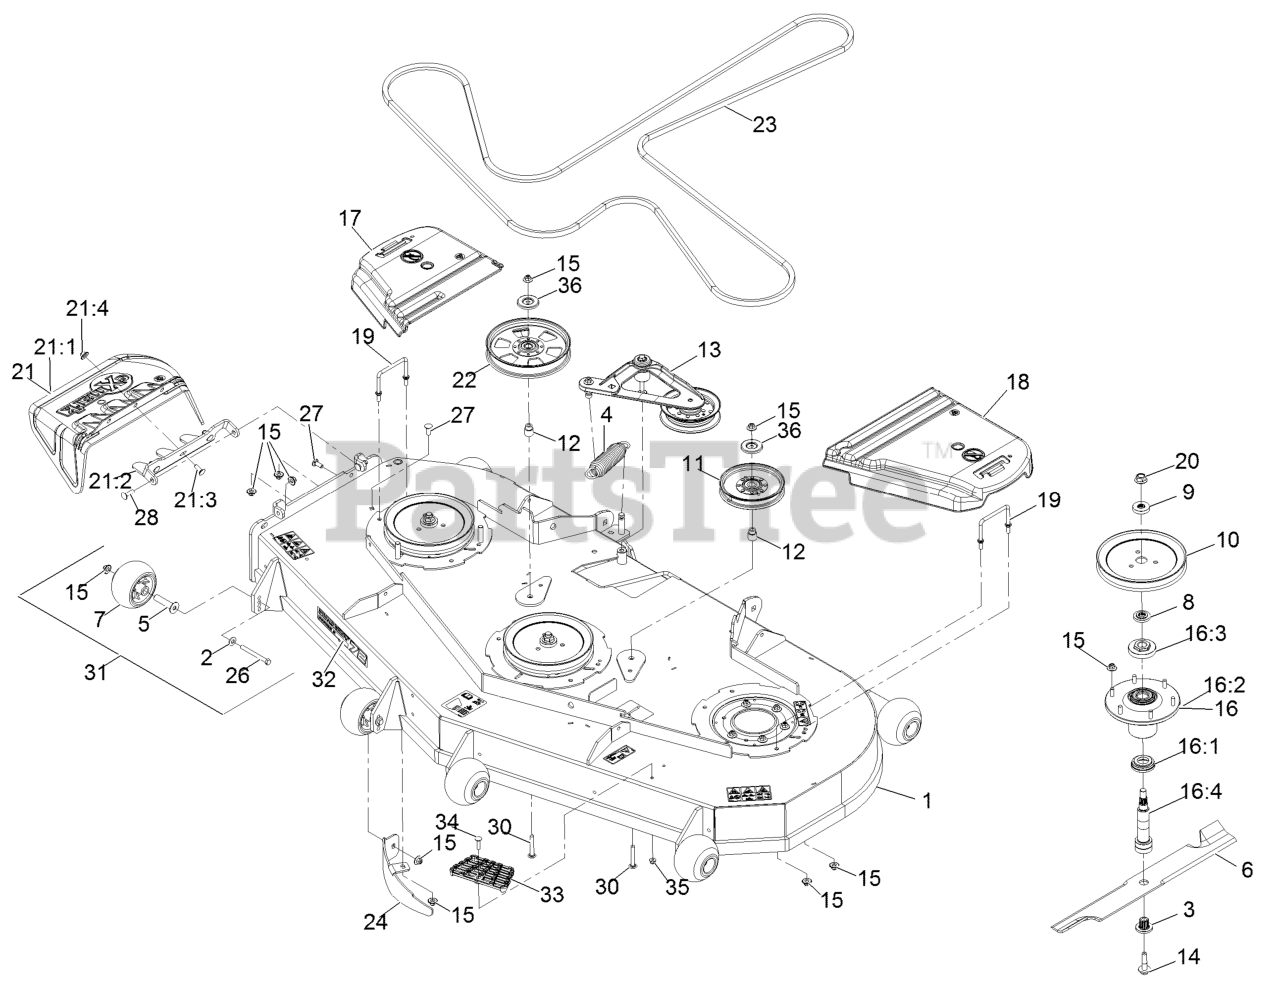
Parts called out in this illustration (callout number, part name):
1	ASM,Deck W/Decals 724
2	Washer-Spring Disc 3/8
3	Bushing, Splined
4	Spring-Extension
5	Axle, Roller
6	Blade-Extreme 2, 24.50"
6	Blade, Notched (72")
6	Blade, Mulching (72")
6	Blade, Low Lift (72")
6	Blade, Solid (72")
7	Roller-Anti-Scalp
8	Spacer, Splined Stepped
9	Spacer, Splined
10	Sheave,Blade Drive 9.00
11	Idler-Pulley, Flat 6.00X0.75
12	Bushing, Idler
13	Deck Idler ASM
14	Screw-Sems 1/2-20 X 2.19
15	Nut-Nyloc 3/8-16 Flg
16	ASM,Spindle Housing
16:1	Guard, Bottom
16:2	Asm, Cutter Housing
16:3	Nut, Spindle 7/8-14
16:4	Spindle,Double Spline
17	Cover-Belt, RH
18	Cover-Belt, LH
19	Wireform-Cover
20	Nut-Flange 5/8-18 Centerlock
21	ASM,Discharge Chute
21:1	Chute, Discharge
21:2	Bracket,Discharge Chute
21:3	Bolt-Carriage 3/8-16 X 1
21:4	Nut-Nyloc 3/8-16 Flg
22	Pulley-Idler, Flat
23	Belt-V
24	Baffle-Dogleg, Lz72
26	Screw-HH 3/8-16 X 3 3/4 GR 8
27	Bolt-Carriage 3/8-16 X 1
28	Bolt-Carriage 3/8-16 X 1 1/4
30	Bolt-Carriage 3/8-16 X 2 1/2
31	Kit, Anti-Scalp Roller
32	Decal, 726
33	Step-Deck
34	Bolt-Carriage 5/16-18 X 1 1/4
35	Nut-Nyloc 5/16-18 Flg
36	Shield-Dust
